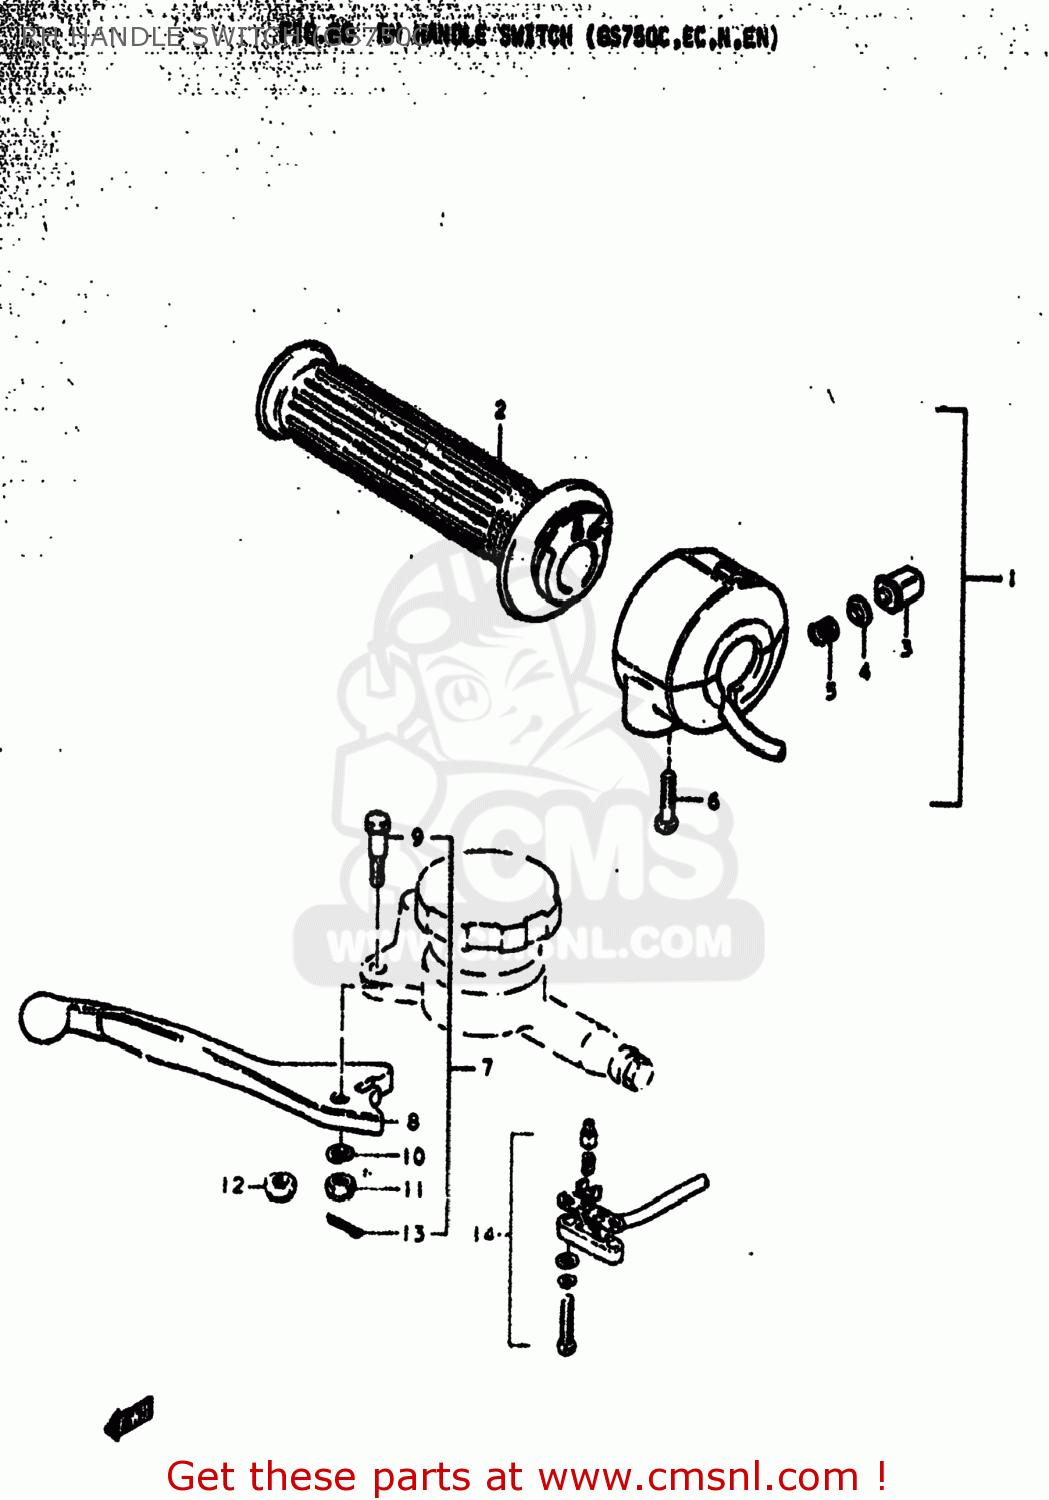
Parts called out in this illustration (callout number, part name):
1	CASE ASSEMBLY,THROTTLE
2	GRIP,THROTTLE
3	BUTTON,HORN
4	CONTACT
5	SPRING
6	SCREW
7	LEVER ASSEMBLY,BRAKE
8	LEVER,BRAKE
9	BOLT,LEVER
10	LOCK WASHER
11	NUT,LEVER FITTNG
12	NUT 6MM
13	COTTER PIN
14	SWITCH ASSY,STOP
